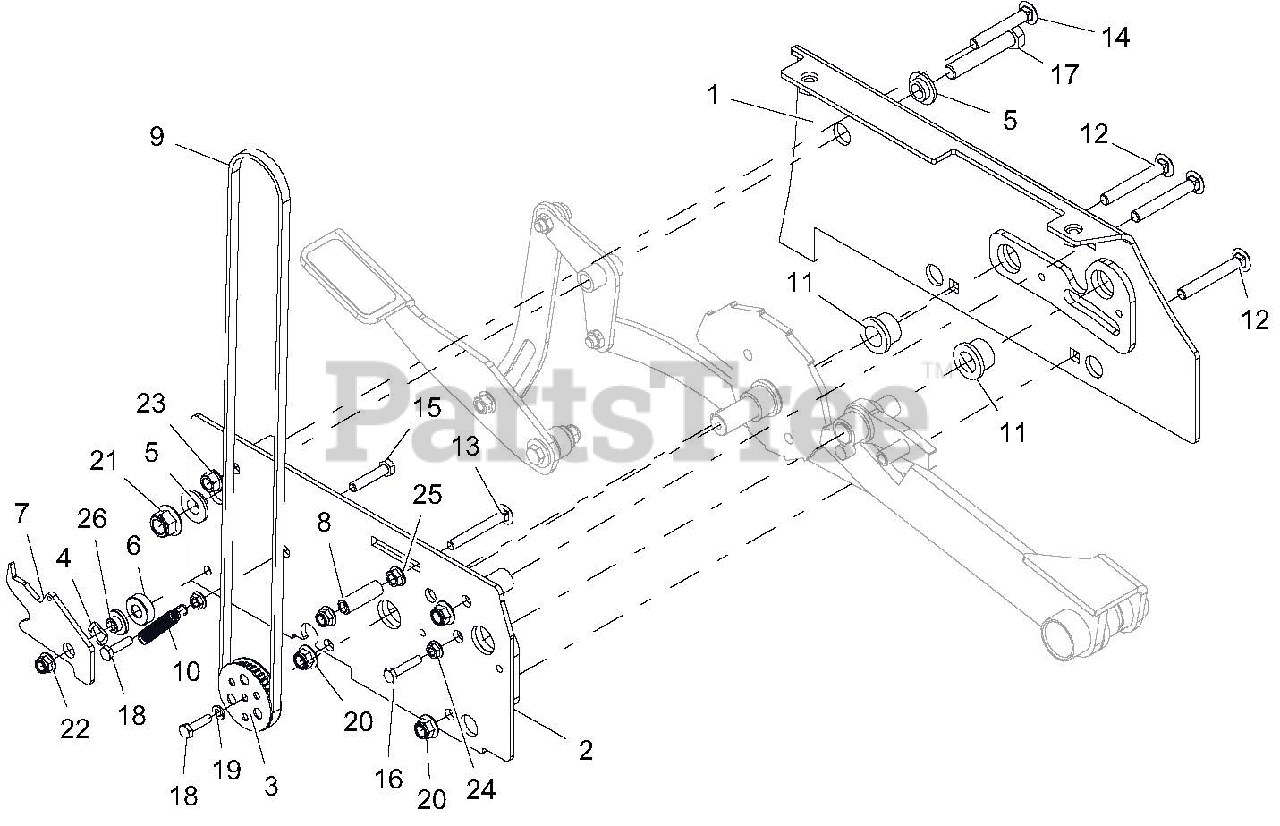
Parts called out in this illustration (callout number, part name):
1	WLDMT, LH BOTTOM TOWER SIDE
2	WLDMT, CAM COVER
3	WLDMT, PULLEY
4	WAVE WASHER .531X.781X.125 FH
5	BSHG, FLANGE .515X.750X.31X1.12
6	SPCR, .375 X 1.00 X .342
7	LATCH, FOOT PEDAL
8	BSHG, SLV .33X.50X1.56
9	BELT, TIMING-LONG
10	SPRG, EXTENSION
11	BUSHING, .750 X 1.00 X .750
12	BLT-RDHDSQNK .38-16X2.75 G5 Y
13	BLT-RDHDSQNK .31-18X2.50 G5 Y
14	BLT-RDHDSQNK .38-16X2.50 G5 Y
15	BLT-HEX .31-18X1.50 GR5 YWZC
16	BLT-HEX .25-20X1.25 GR5 YWZC
17	BLT-HEX .50-13X2.75 GR5 YWZC
18	BLT-HEX .25-20X1.00 GR5 YWZC
19	WSHR-LK .25X.062 REG YWZC
20	NUT-LK-NYL-FLG .38-16 YWZC
21	NUT-LK-NYL-FLG .50-13 YWZC
22	NUT-LK-NYL-FLG .31-18 YWZC
23	NUT, LK-TOP-FLG .38-16 YWZC
24	@NUT-SPNLK-FLG .25-20 YWZC
25	@NUT-SPNLK-FLG .312-18 YWZC
26	BSHG, FLG .32X.500.344X.880
